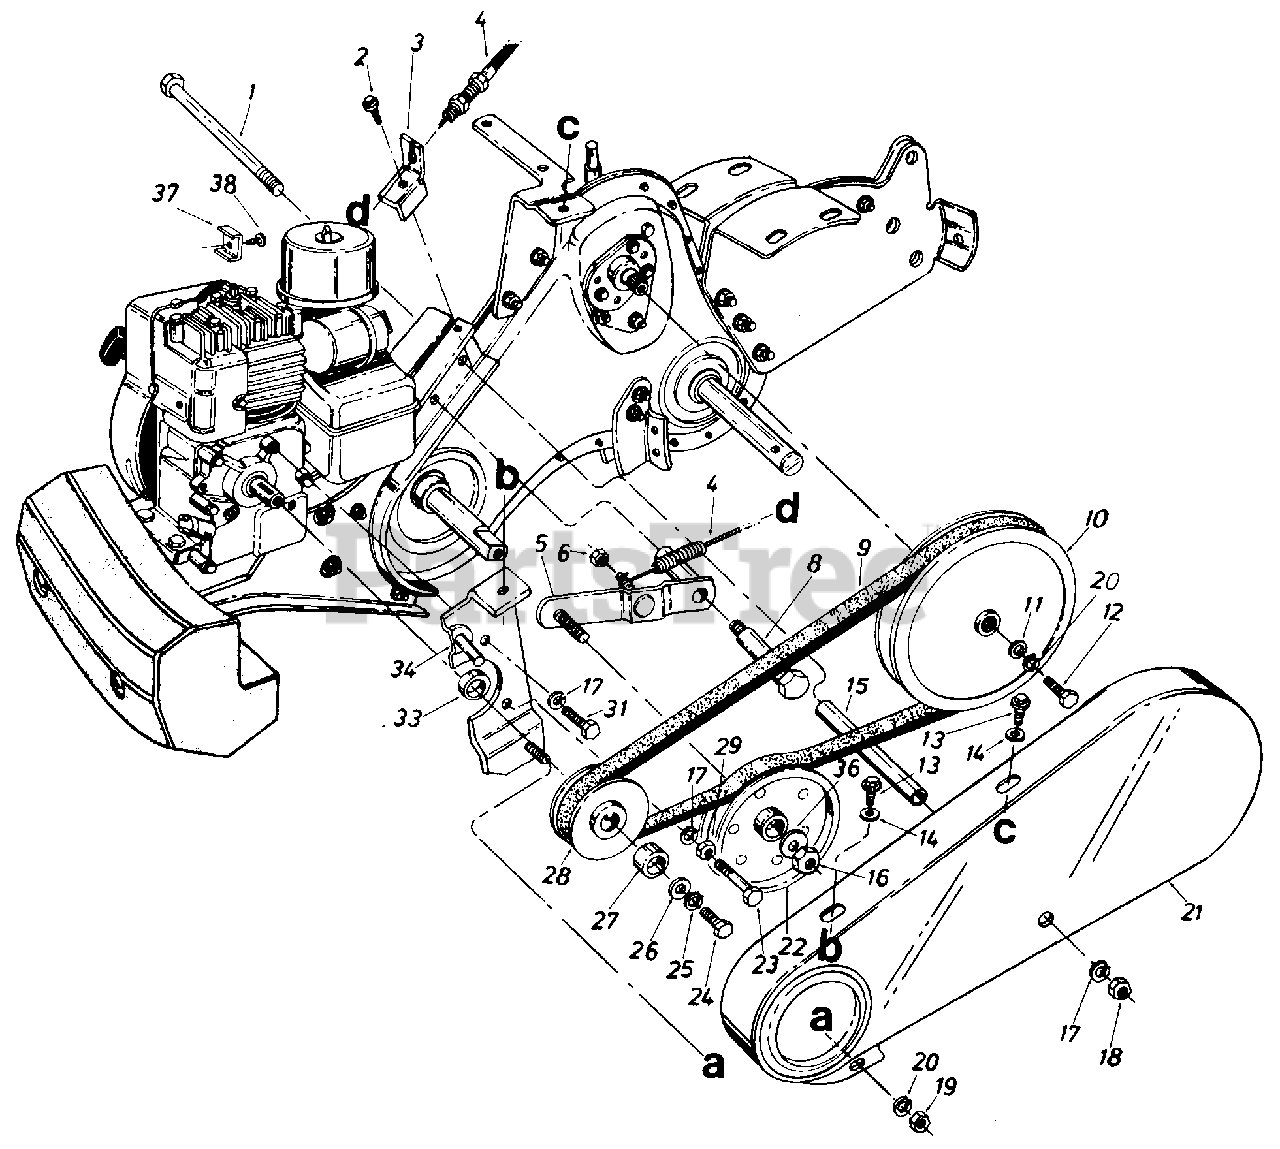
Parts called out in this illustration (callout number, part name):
1	Hex Bolt 5/16-18 x 4.75" Lg.-Gr. 2
2	Hex Wash. TT-Tap Scr. 5/16-18 x .62" Lg.
3	Bracket Clutch Cable
4	Clutch Control Cable 53" Lg.
8	Shld. Bolt .500" Dia. x 2.27"
9	"V"-Belt 1/2" x 581' Lg.
10	"V"-Pulley Split 5/8" I.D.
11	Fl-Wash. 1/4" I.D. x .93" O.D.
12	Hex Bolt 1/4-28 x .75" Lg.
13	Hex Wash. Hd. S-Tap Scr. 1/4-20 x .50" Lg.
14	Fl-Wash. .281" I.D. x .625"
15	Spacer 3/8" I.D. x 3.38" Lg.
16	Hex Cent. L-Nut 3/8-24 Thd.
17	L-Wash. 5/16" I.D.
18	Fl-Wash. 5/16" I.D.
19	Hex Nut 1/4-20 Thd.
20	L-Wash. 1/4" I.D.
22	Fl-Idler w/Flanges 3.75" O.D.
23	Hex Bolt 5/16-24 x 1.75"
24	Hex Bolt 3/8-24 x 1.00" Lg.
25	L-Wash. 3/8" I.D.
26	Fl-Wash. 3/8" I.D. x 1.00"
27	Spacer .758" I.D. x .990"
28	Engine Pulley
29	Hex Nut 5/16-24 Thd.
31	Hex Bolt 5/16-24 x .62" Lg.
33	Spacer 1.0" O.D. x .790" I.D. x .350
37	Casing Clamp
38	Hex Sems Scr. #10-32 x .62"
